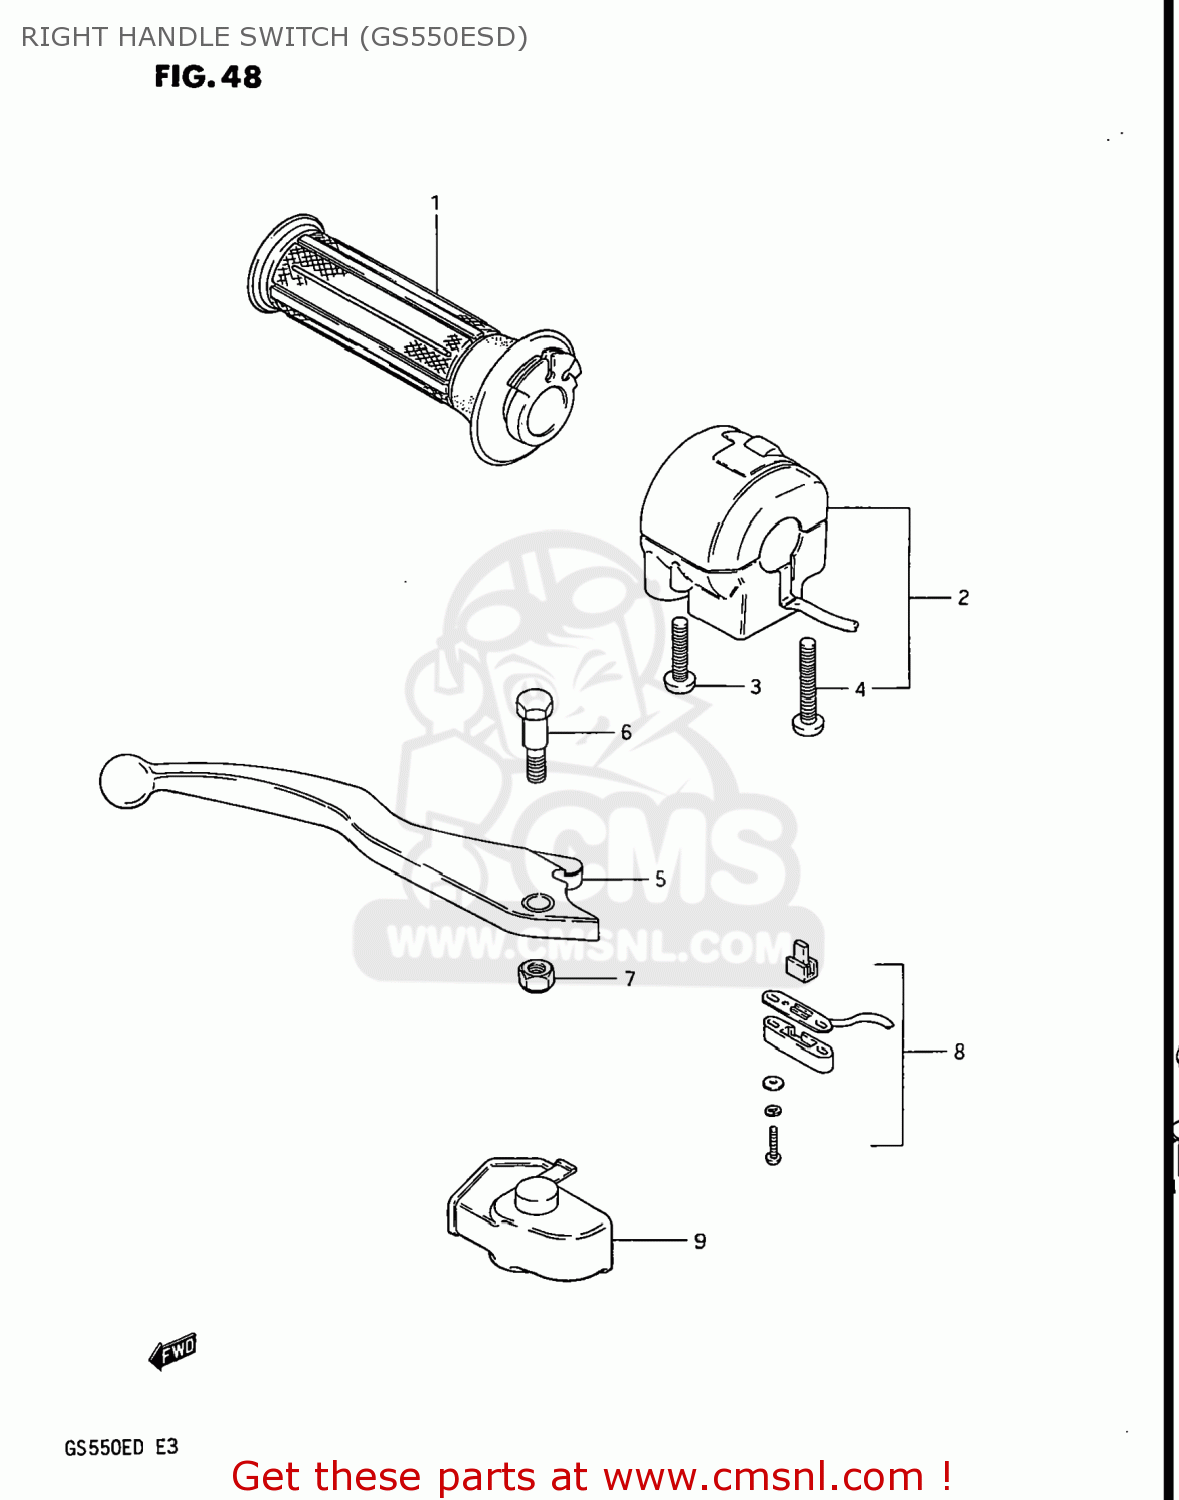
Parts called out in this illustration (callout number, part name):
1	GRIP,THROTTLE
2	SWITCH ASSEMBLY,HANDLE,RIGHT
3	SCREW
4	SCREW
5	LEVER,BRAKE
6	BOLT,LEVER PIVOT
7	NUT 6MM
8	SWITCH ASSEMBLY
9	COVER,BRAKE LEVER
